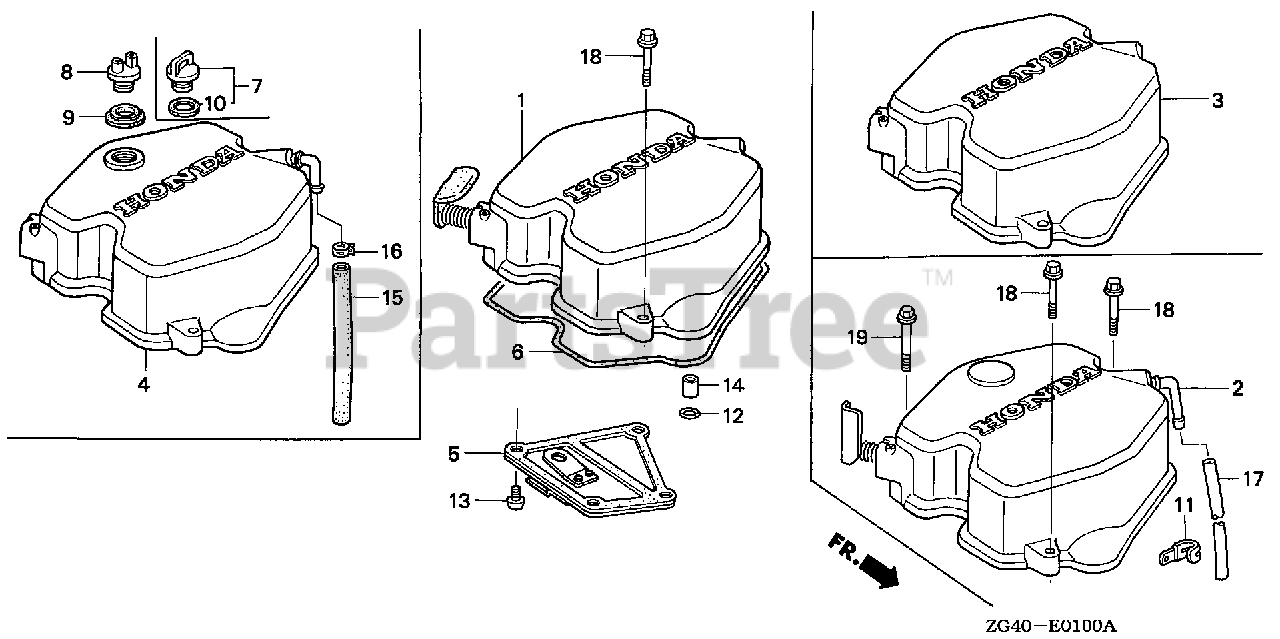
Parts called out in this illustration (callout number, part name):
1	COVER, CYLINDER HEAD (SEL)
5	PLATE, BREATHER
6	O-RING, HEAD COVER
13	SCREW, PAN (6X8)
14	PIN, DOWEL (6X10)
18	BOLT, FLANGE (6X32)
